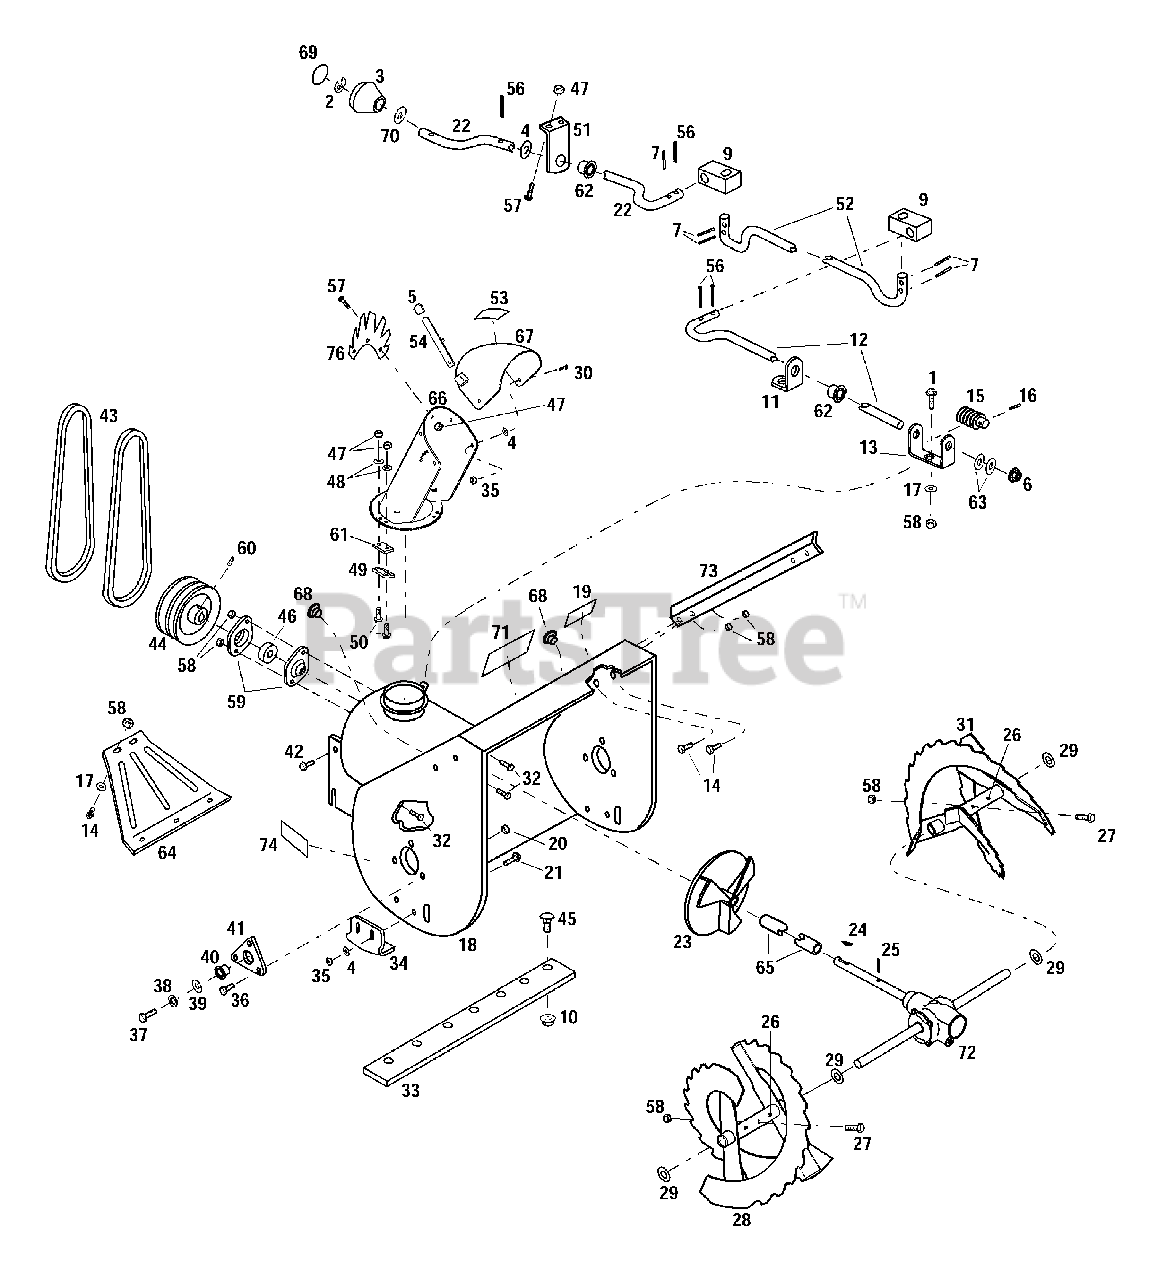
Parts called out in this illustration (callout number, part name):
1	Flange Bolt, 5/16-18 x 3/4
2	Retainer, 3/8
4	Flat Washer, 3/8
6	Flange Nut, 3/8-16
7	Roll Pin, 1/8 x 3/4
9	Swivel Block
10	Flange Nut, 5/16-18
11	Crank Support
12	Chute Control Shaft
13	Gear Support
14	Hex Head Cap Screw, 5/16-18 x 3/4
15	Worm Gear
16	Drive Pin, 3/32 x 3/4
17	Flat Washer, 5/16
18	Collector Housing Assembly
19	Warning Decal
20	Lock Nut, 1/4-20
21	Carriage Bolt, 3/8-16 x 3/4
22	Chute Control Crank
23	Impeller Fan
24	Hy Pro Key, 3/16 x 3/4
25	Roll Pin, 1/4 x 1-1/4
26	Grease Fitting
27	Shear Bolt Kit
28	26" Auger, R.H.
29	Special Washer, 1-1/64
30	Hex Head Cap Screw, 3/8-16 x 3/4
31	26" Auger, L.H.
32	Carriage Bolt, 5/16-18 x 3/4
33	Scraper Blade
34	Skid Shoe
35	Lock Nut, 3/8-16
36	Hex Head Cap Screw, 1/4-20 x 5/8
37	Hex Head Cap Screw, 1/2-13 x 3/4
38	Lock Washer, 1/2
39	Flat Washer, 1/2
40	Flange Bearing
41	Bearing Support
42	Flange Bolt, 3/8-16 x 1/2
43	V-Belt
44	Auger Sheave
45	Carriage Bolt, 5/16-18 x 5/8
46	Ball Bearing
47	Lock Nut, #10-24
48	Flat Washer, #10
49	Hold-Down Clip
50	Sems Screw, #10-24 x 7/8
51	Chute Control Support
52	Chute Crank Rod
53	Warning Decal
54	Adjusting Lever
56	Cotter Pin, 3/32 x 1/2
57	Truss-Head Bolt, #10-24 x 3/8
58	Lock Nut, 5/16-18
59	Flange Bearing
60	Set Screw, 5/16-18 x 3/4
62	Nylon Bushing
63	Nylon Washer
64	Housing Support
65	Sleeve
66	Discharge Chute Assembly
67	Discharge Cap
68	Button Plug
69	Spun Silver Inlay
70	Flat Washer, 3/8
71	Housing Logo Decal
72	Gear Case Assembly
73	Drift Slicer (complete kit)
74	Auger Width Decal
76	Chute Deflector
106	Loctite #242, .02 oz
